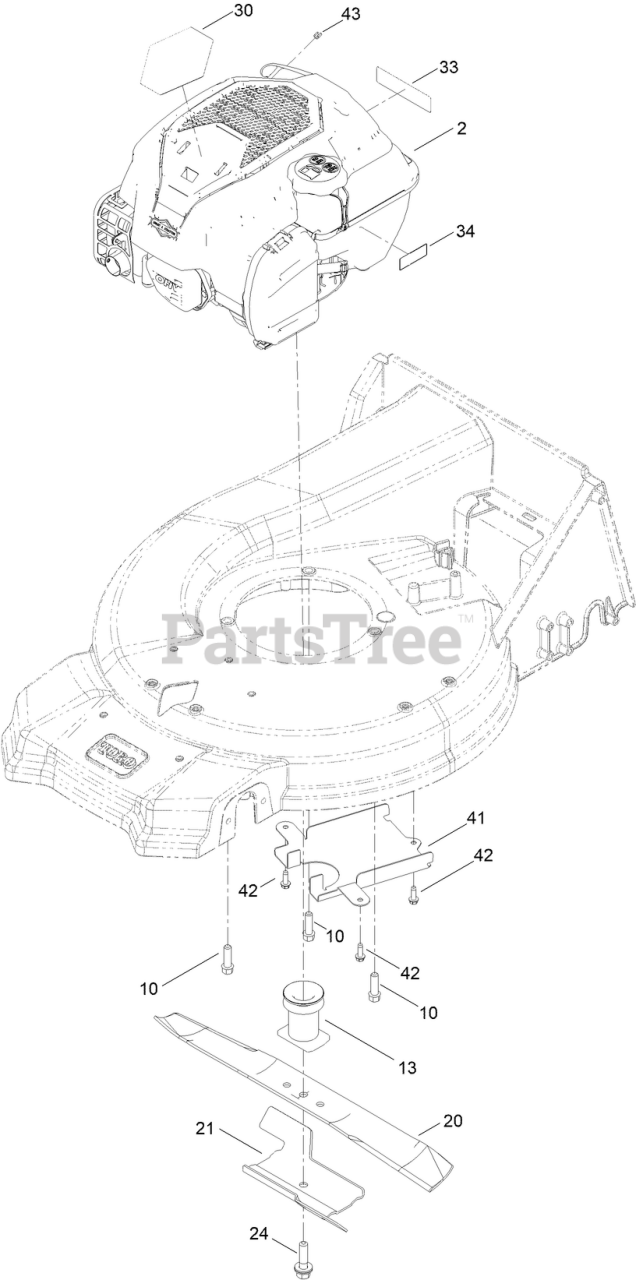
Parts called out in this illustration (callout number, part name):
10	SCREW-TAPTITE
13	DRIVER-BLADE
20	BLADE-21IN, RECYCLING
21	ACCELERATOR-BLADE
24	BOLT-BLADE
30	DECAL-BRIGGS 725 EXI SS
33	DECAL-ARRESTOR, SPARK
34	DECAL-LEVEL, FUEL
41	COVER-BELT, BOTTOM
42	SCREW-HWHTF
43	STOP-ROPE
